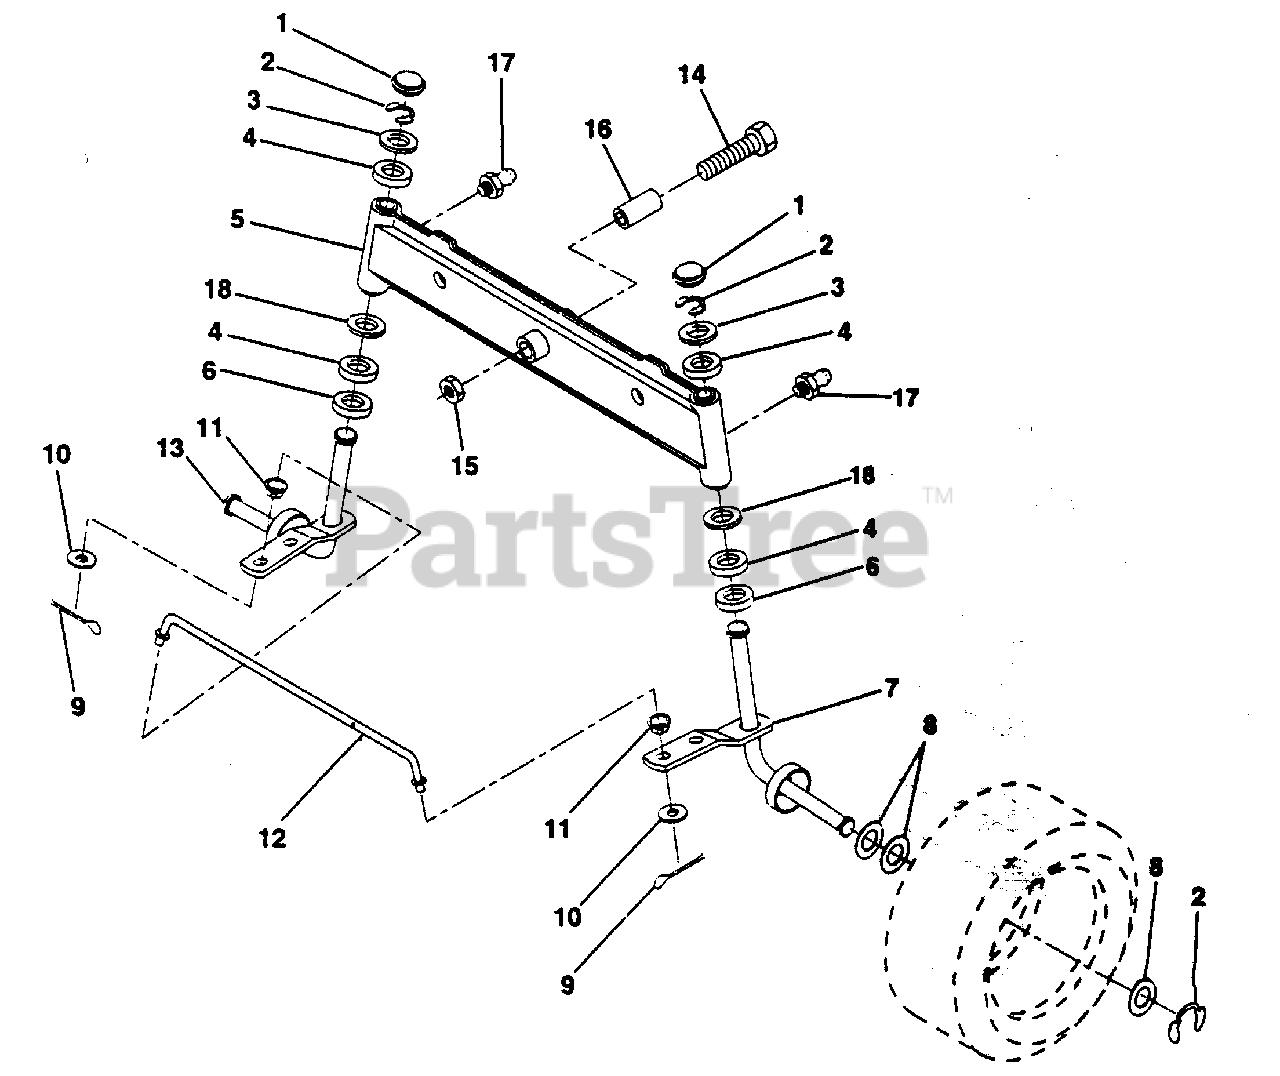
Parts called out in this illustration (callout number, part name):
1	Cap, Spindle (AYP part number)
2	Ring, Clip (AYP part number)
3	Washer 25/32 x 1-5/8 x 16 Gauge (AYP part number)
4	Bearing (AYP part number)
5	Axle, Front (AYP part number)
6	Bearing, Thrust (AYP part number)
7	Spindle Assembly, R.H.
8	Washer 25/32 x 1-1/4 x 16 Gauge (AYP part number)
9	Pin, Cotter 1/8 x 3/4 (AYP part number)
10	Washer 13/32 x 13/16 x 16 Gauge (AYP part number)
11	Bushing (AYP part number)
12	Tie Rod (AYP part number)
13	Spindle Assembly, L.H. (AYP part number)
14	Bolt Hex 5/8-11 Unc x 3-1/2 (AYP part number)
15	Nut Lock Flange 5/8-11 Unc (AYP part number)
16	Spacer Bearing (AYP part number)
17	Fitting Grease (AYP part number)
18	Washer 27/32 x 1-1/4 x 16 Ga. (AYP part number)
